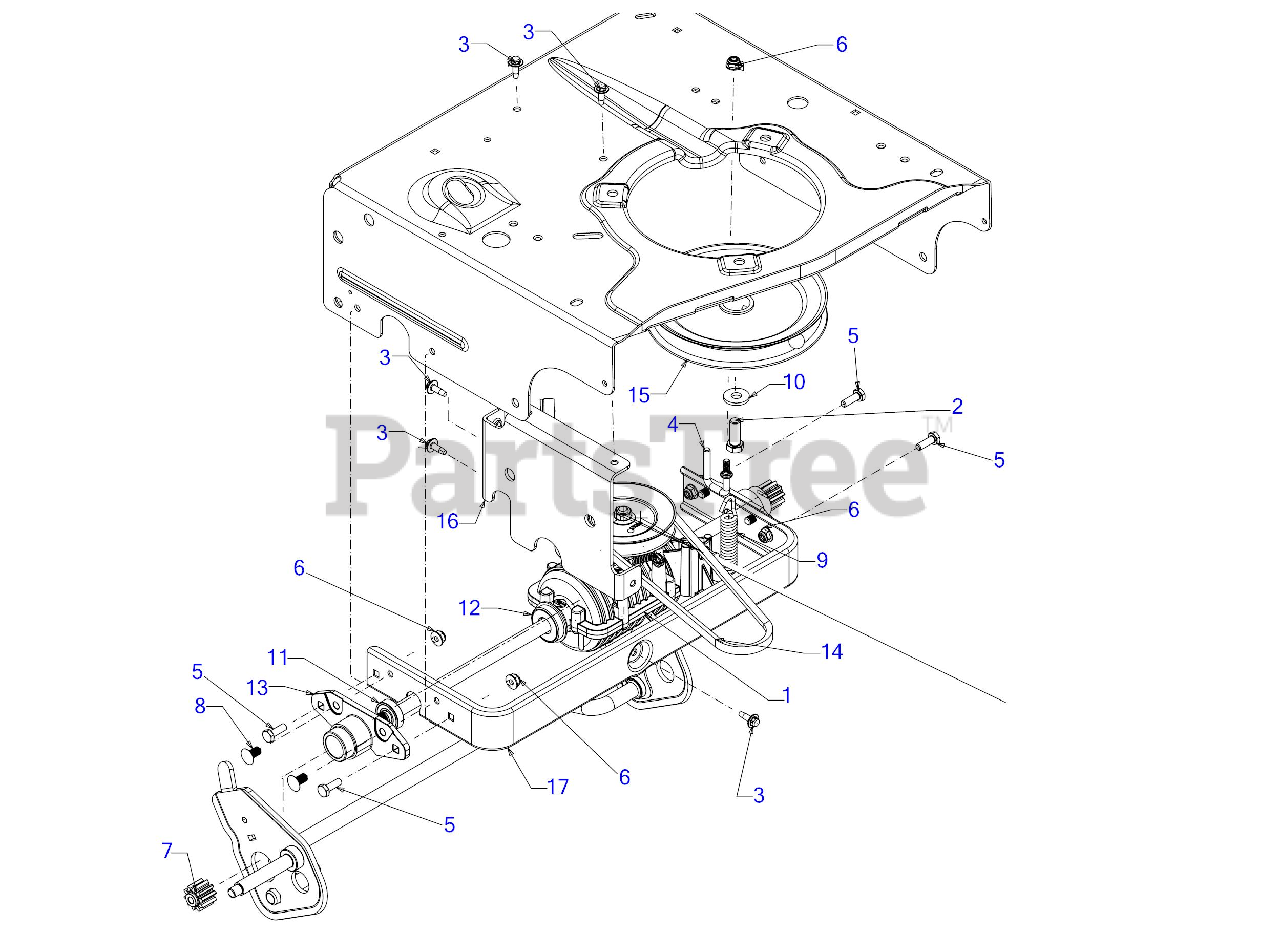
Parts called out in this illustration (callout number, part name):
1	TRANSMISSION
2	SCREW 3/8-24 x 1.00 GR5
3	SCREW M6-1 x .625
4	EYE BOLT SPRING GUIDE 1/4-20
5	SCREW 1/4-20X.75 GR5
6	FLANGE LOCK NUT
7	SPUR GEAR 10T
8	RETAINER PAN CLIP
9	EXTENSION SPRING
11	BALL BEARING
12	ROLLER BEARING .5X1.37X.44
13	DRIVE BEARING
14	BELT 3/8 x 24.68"
15	ENGINE PULLEY
